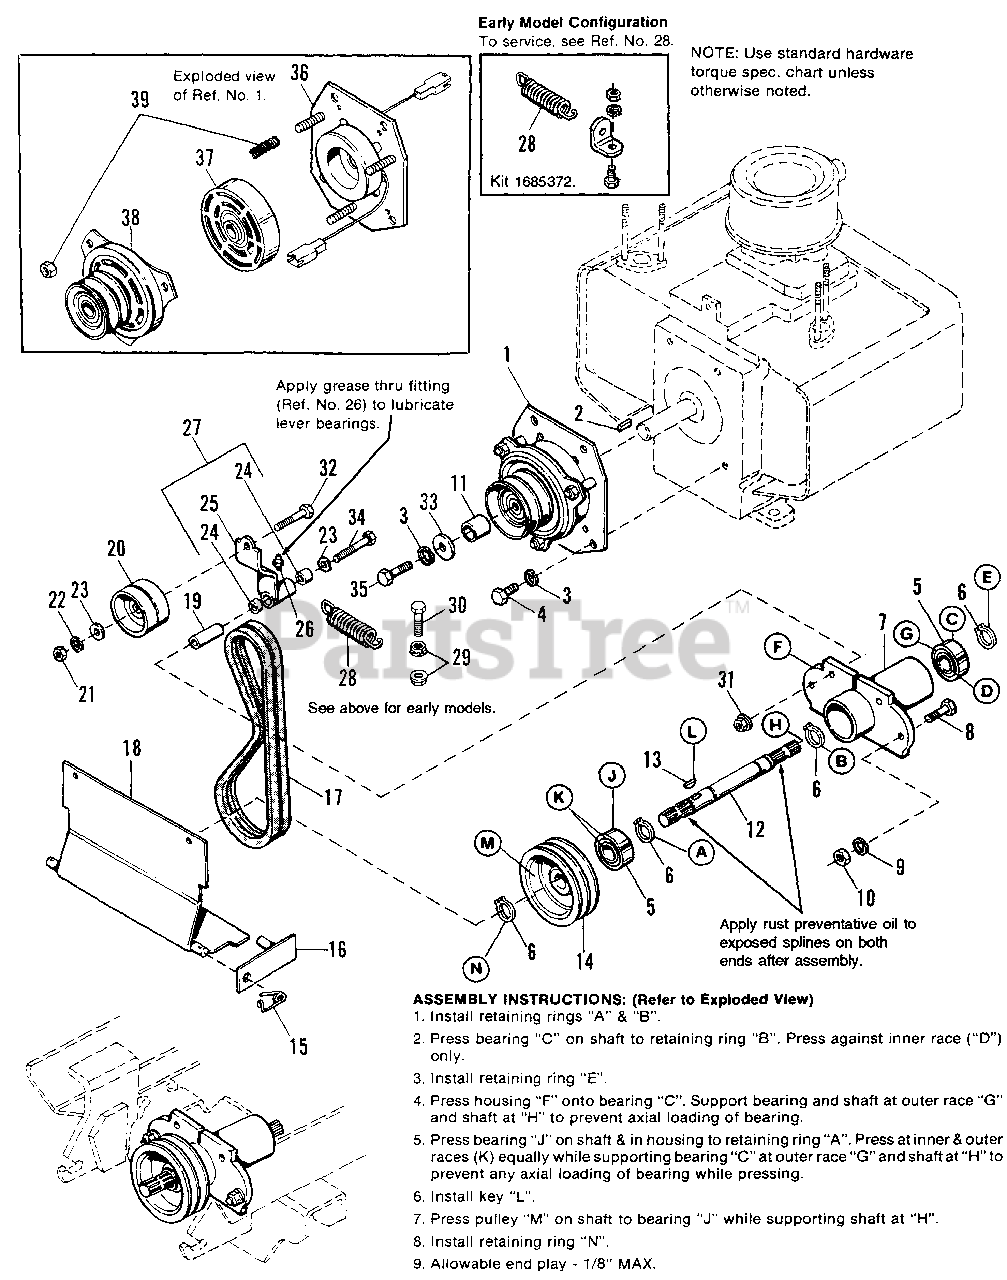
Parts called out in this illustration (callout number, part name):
1	CLUTCH, Electric (Incl. Ref. Nos. 36, 37, 38 & 39)
2	KEY, Sq., 1/4 x 1/4 x 29/32
3	LOCKWASHER, 7/16
4	CAPSCREW, Hex Hd., 7/16-14 x 1
5	BEARING, Ball, 1-3/16 x 2-7/16 x 5/8
6	RING
7	HOUSING & PLATE ASSY.
8	CAPSCREW, Hex Hd., 1/2-13 x 1-1/4, Gr. 5
9	LOCKWASHER, 1/2
10	NUT, Hex, 1/2-13
11	SPACER, 1/18 I.D. x 1-3/8 O.D. x 5/16
12	SHAFT, Spline, PTO
13	KEY, HI PRO, 1/4 x 3/4
14	PULLEY, PTO Drive
15	CLIP, Pin, Safety
16	LINK & PIN ASSY., Guard
17	BELT SET, PTO Drive (Matched Set of 2)
18	GUARD ASSY.
19	SPACER, 3/8 x 5/8 x 1-3/4
20	PULLEY, Idler, 3-1/4 Dia.
21	NUT, Hex, 3/8-16
22	LOCKWASHER
23	WASHER, 13/32
24	BUSHING, Idler Arm
26	FITTING, Grease
27	IDLER ARM ASSY. (Incl. Ref. Nos. 24 & 25)
28	SPRING, Tension (Later Models-refer to illustration)
28	SPRING, Tension (Early Models-refer to illustration)
29	NUT, Hex, Flange Whizlock 3/8-16
30	CAPSCREW, Hex Hd., 3/8-16 x 1-1/4
31	NUT, Hex, Flange, 3/8-16
32	SCREW, Hex Hd., 3/8-16 x 2
33	WASHER, 15/32 ID x 1-3/4 OD x 1/4
34	SCREW, Hex Hd., 3/8-16 x 2-1/2, Gr. 5
35	SCREW, Hex Hd., 7/16-20 x 1-1/2, Gr. 5
36	FIELD ASSEMBLY
37	ROTOR ASSEMBLY
38	ARMATURE & BRAKE DRUM
39	ACCESSORY KIT (Nut & Springs)
